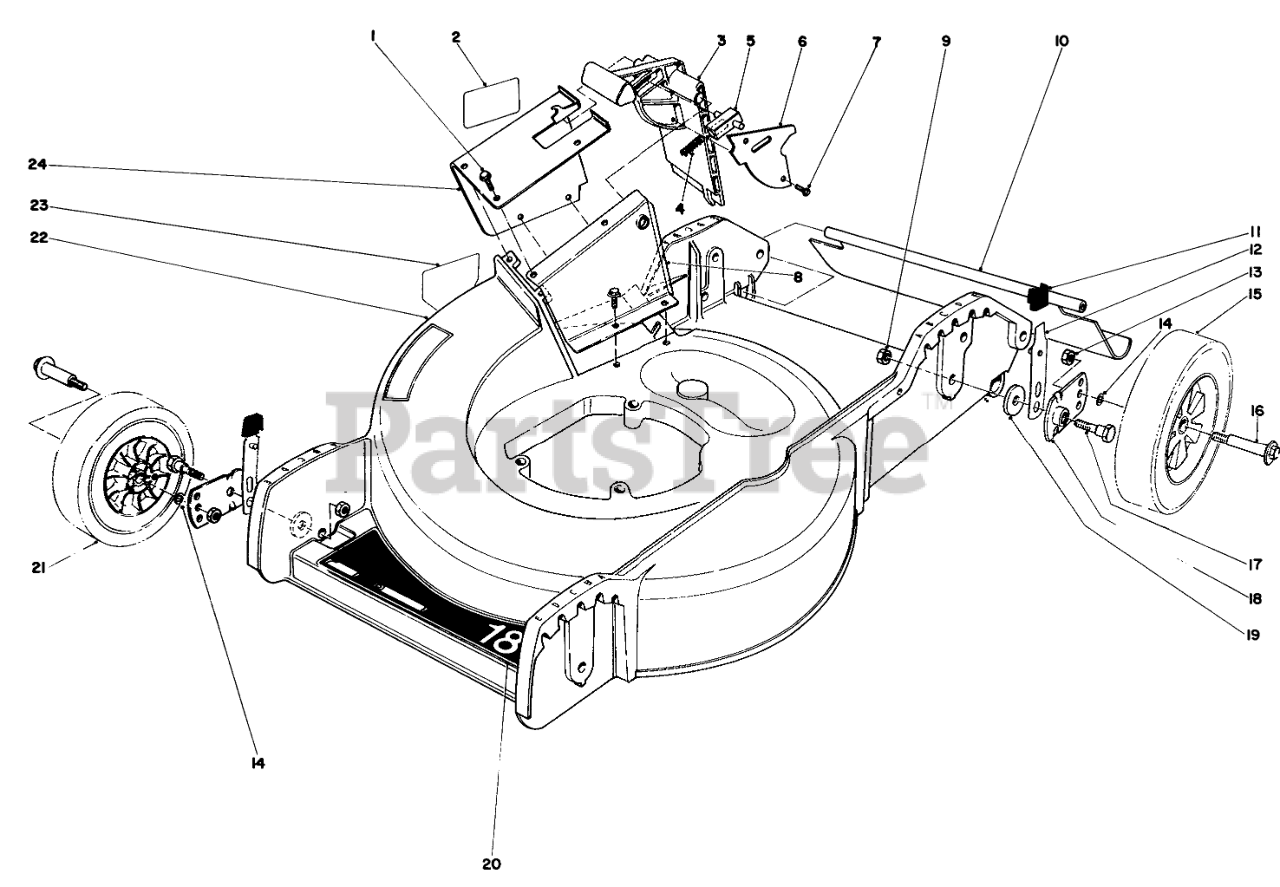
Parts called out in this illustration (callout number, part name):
1	SCREW
2	Danger Decal
3	Door Mulching
4	SPRING-COMPRESSION, LATCH
5	Door Latch
6	Cover Door
8	Inner Tunnel
9	Nut
10	SHIELD - TRAILING
11	KNOB-ARM
12	SPRING ARM ASM
13	Nut
14	WASHER
15	WHEEL TIRE ASM 8 IN
16	BOLT-WHEEL
17	PIVOT SCREW
18	PIVOT ARM ASSY
19	PIVOT WASHER
20	Decal-Rear Bagger
21	WHEEL TIRE ASM 7 IN
22	Housing (Incl. Ref. #23)
23	DECAL-DANGER
24	Tunnel-Outer(Incl. Ref. #2)
